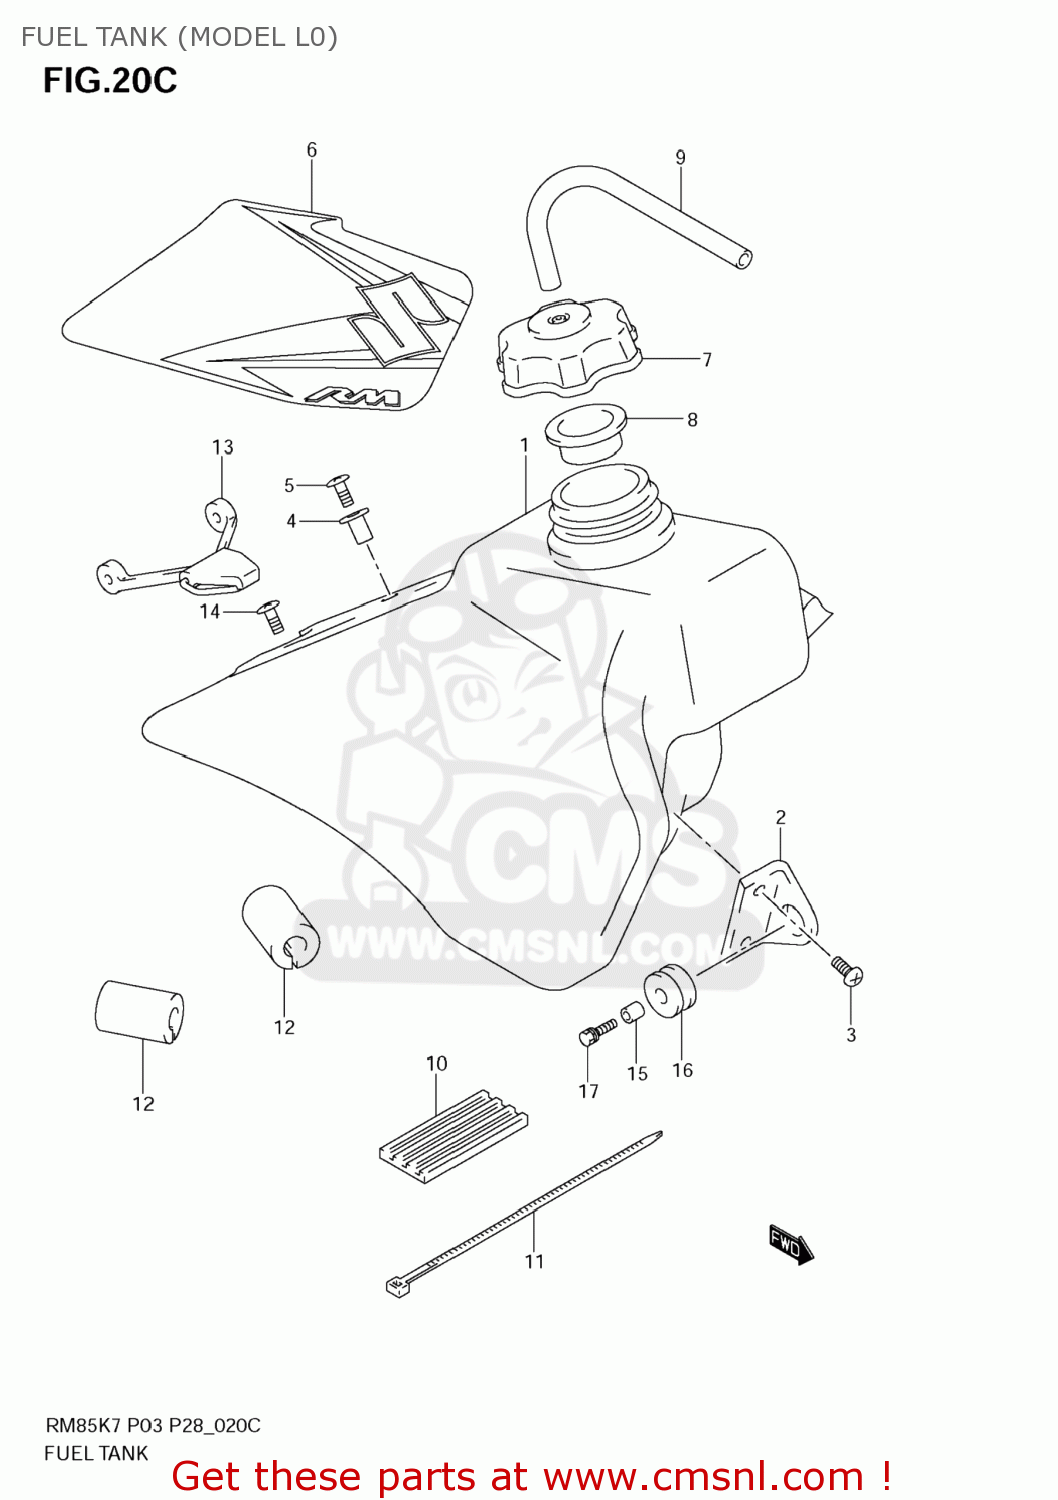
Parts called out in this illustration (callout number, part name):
1	TANK,FUEL(YELLOW)
2	BRACKET,FUEL TANK FR
3	SCREW
4	HOOK,SEAT FR
5	SCREW
6	TAPE SET,FUEL TANK
7	CAP,FUEL TANK FILLER
8	GASKET,CAP (NAS)
9	HOSE(5X8.2X600)
10	CUSHION,FUEL TANK UPR FR
11	CLAMP(L:250)
12	CUSHION,FUEL TANK UPR RR
13	BAND,FUEL TANK RR
14	SCREW(6X13.5)
15	SPACER(6.5X9X13.5)
16	CUSHION,MUFFLER
17	BOLT(6X35)
